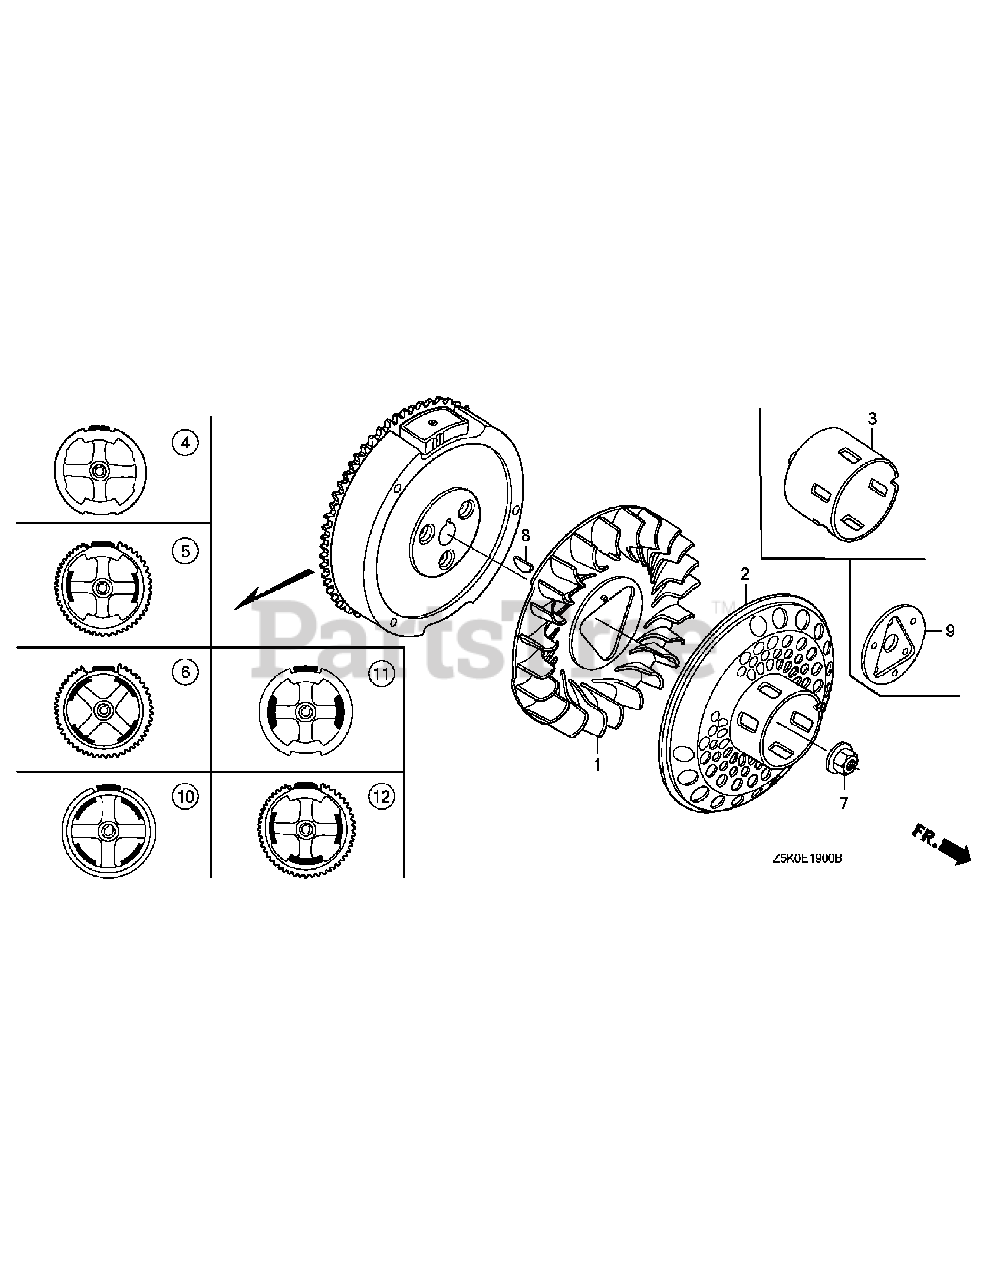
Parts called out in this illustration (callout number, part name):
1	Fan, Cooling
2	Pulley Comp., Starter (Screen Grid)
3	Pulley, Starter
4	Flywheel Comp.
5	Flywheel Comp.(Starter Motor)
6	Flywheel Comp.(4Pole)
7	Nut, Special, 16Mm
8	Key, Special Woodruff, 25X18
9	Plate, Cooling Fan Setting
10	Flywheel Comp.(18A)
11	Flywheel Comp.(Lamp)
12	Flywheel Comp.(Sel)
